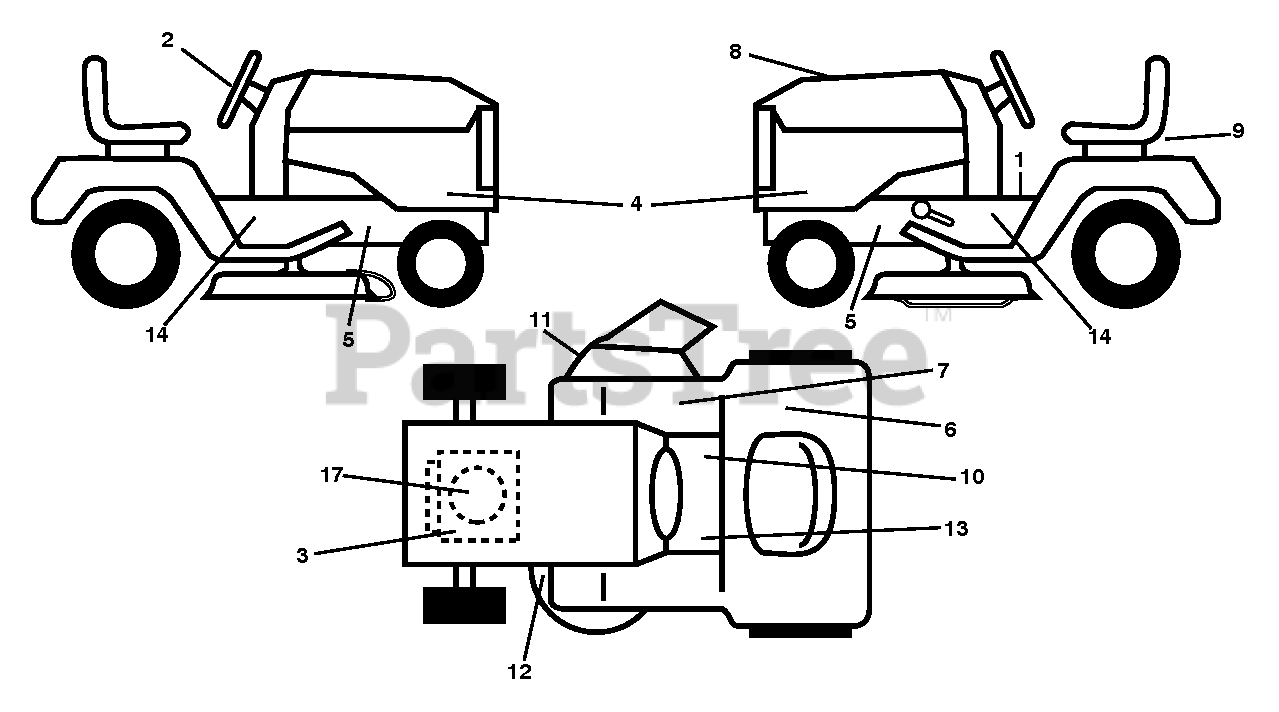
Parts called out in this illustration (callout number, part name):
9	DECAL BTRY SYMBOLS
10	DECAL PARK BRAKE
11	DECAL, WARN. DEFLECT/CTFGR
